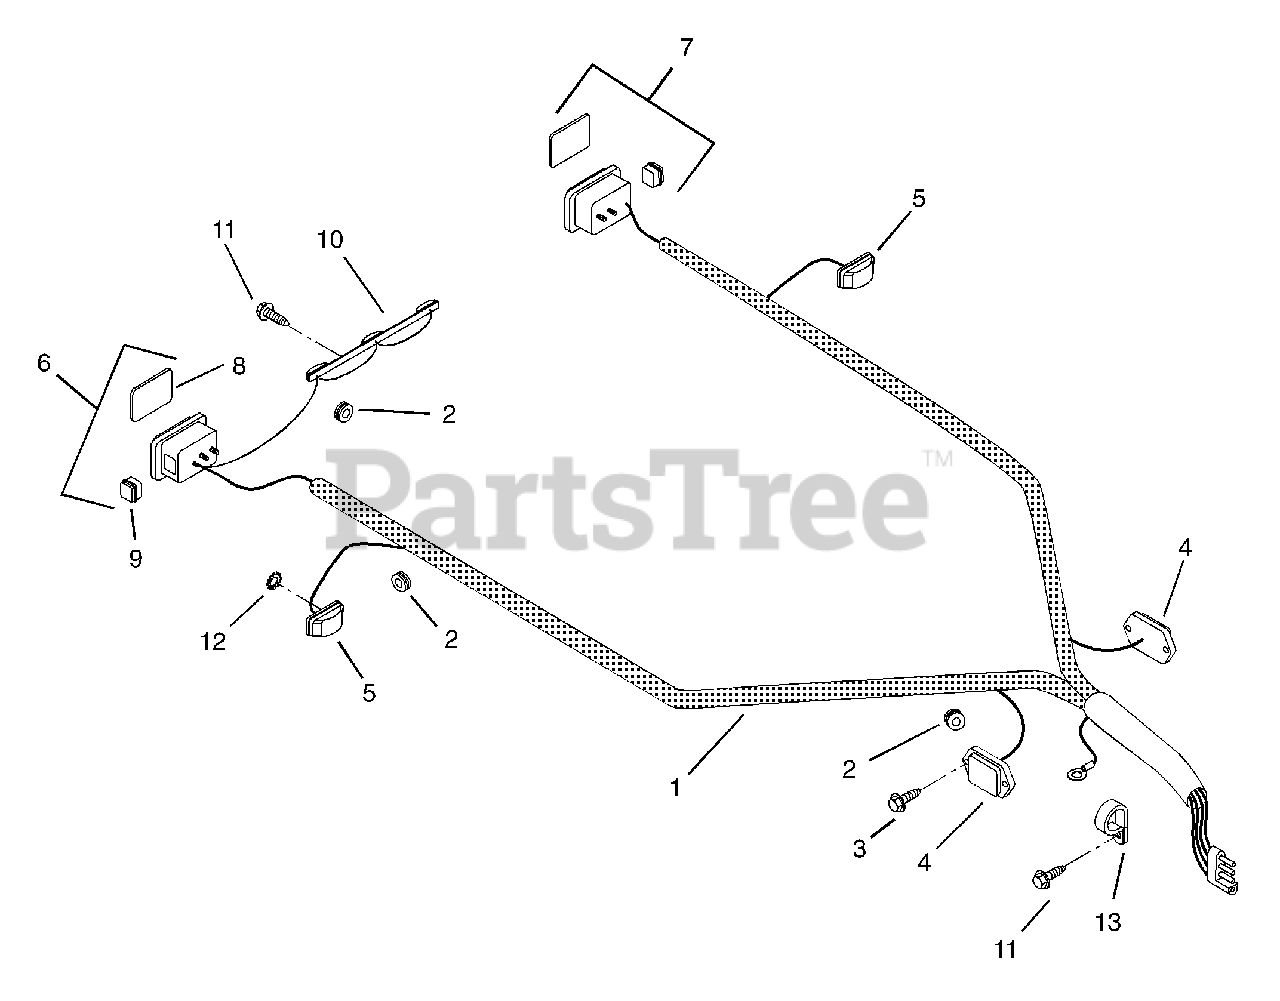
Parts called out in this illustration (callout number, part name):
1	Wiring Harness-Trailer Lights
2	Grommet .188 x .500 Inside Diameter
3	Screw-Tapping 10-24 x .50 Hex Washer Head
4	Light-Side Marker-Ear Mount
5	Light-Amber-Stud Mount
6	Tail Light-Right Hand
7	Tail Light-Left Hand
8	Lens-Tail Light Replacement
9	Lens-S/M Replacement
10	Light Bar-ID Bar
11	Screw-Tapping-Hex Washer Head .25 x .50
12	Washer-Locking-External .262 x .502 x .026
